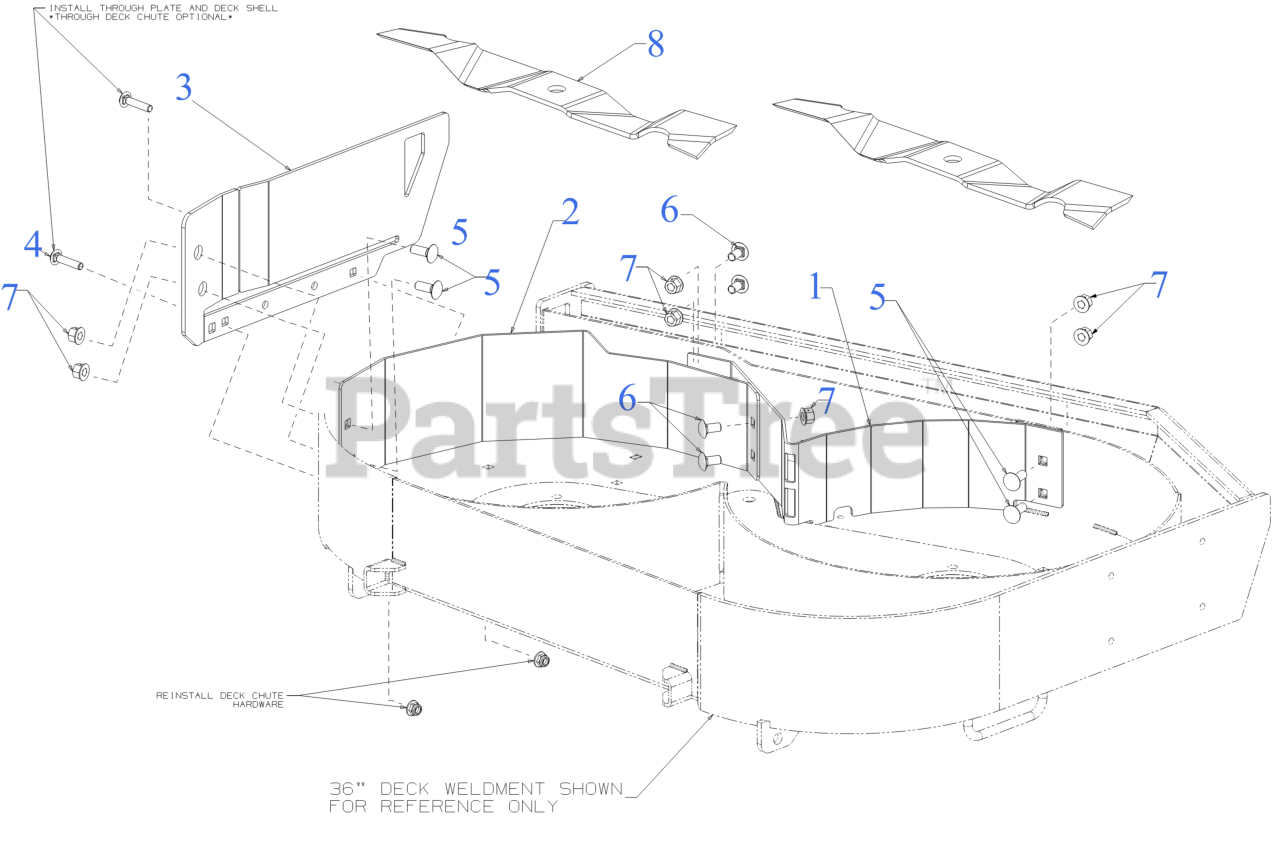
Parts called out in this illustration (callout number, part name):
3	BLOCKER PLATE 36"
4	CARRIAGE BOLT 5/16-18 x 1.50
5	CARRIAGE BOLT 3/8-16 x 1.00 GR5
6	CARRIAGE BOLT 3/8-16 x .75
7	NUT-CTRLCK FLG HEX
8	18.5" BLADE (MULCHING)
